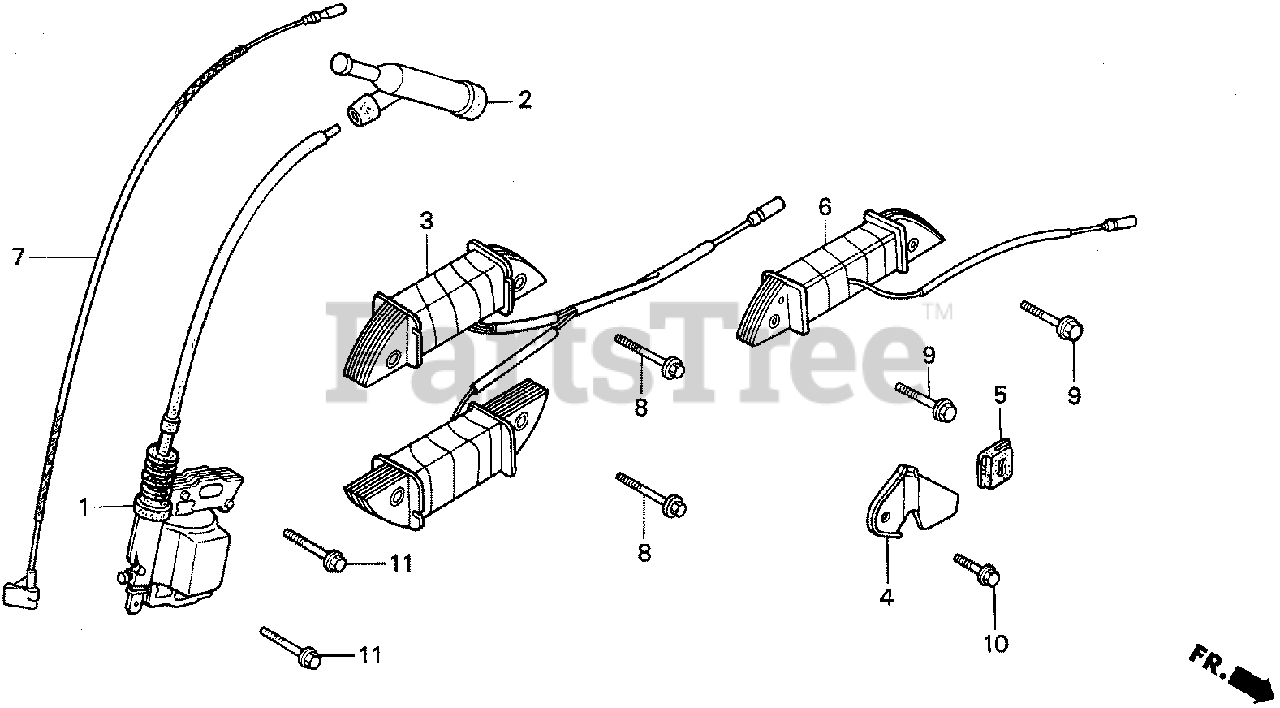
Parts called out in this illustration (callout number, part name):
1	COIL ASSY., IGNITION
2	CAP ASSY., NOISE SUPPRESSOR
7	WIRE, STOP SWITCH (370MM)
11	BOLT, FLANGE (6X25)
